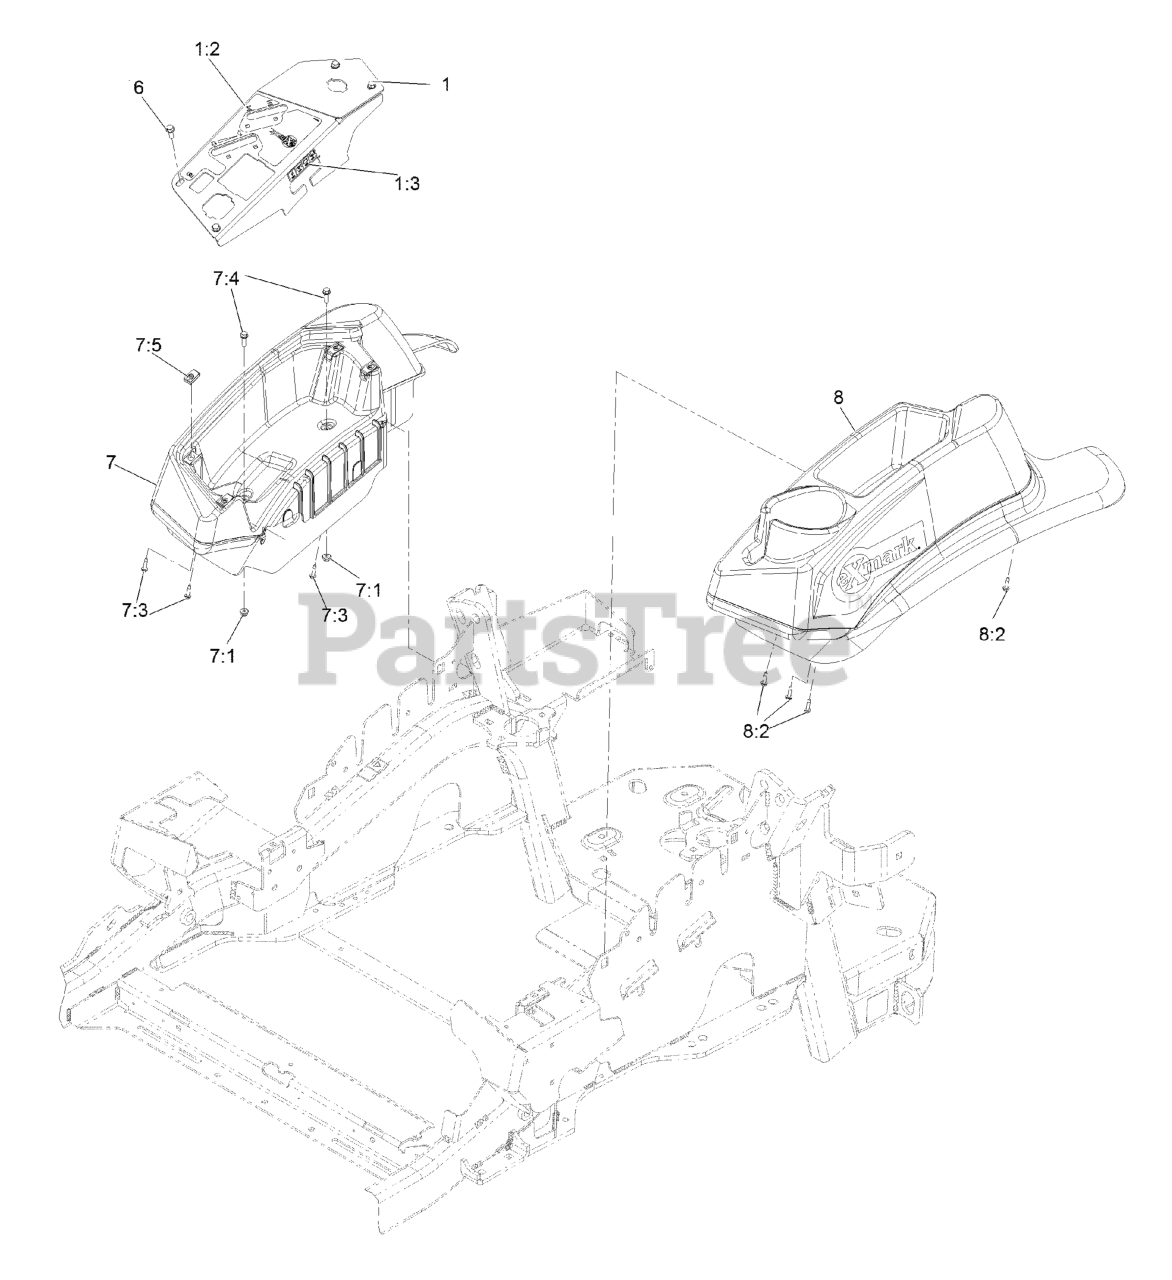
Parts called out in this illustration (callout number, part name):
1	CONSOLE,PANEL W/DECAL
1:2	DECAL-CONTROL PANEL NON-E
1:3	DECAL-FUSES
2	ASM,CHOKE CABLE
3	ASM,THROTTLE CABLE
4	BOLT-CARR
5	NUT-LOCK, NI
6	SCREW-HWH
7	CONSOLE,RH NARROW ASM
7:3	SCREW,THD FORM,HWH
7:4	SCREW-HWH
8	CONSOLE.LH NARROW ASM
8:2	SCREW,THD FORM,HWH
9	CLAMP-HOSE
10	CLAMP-HARNESS
11	CLIP-LOOM
